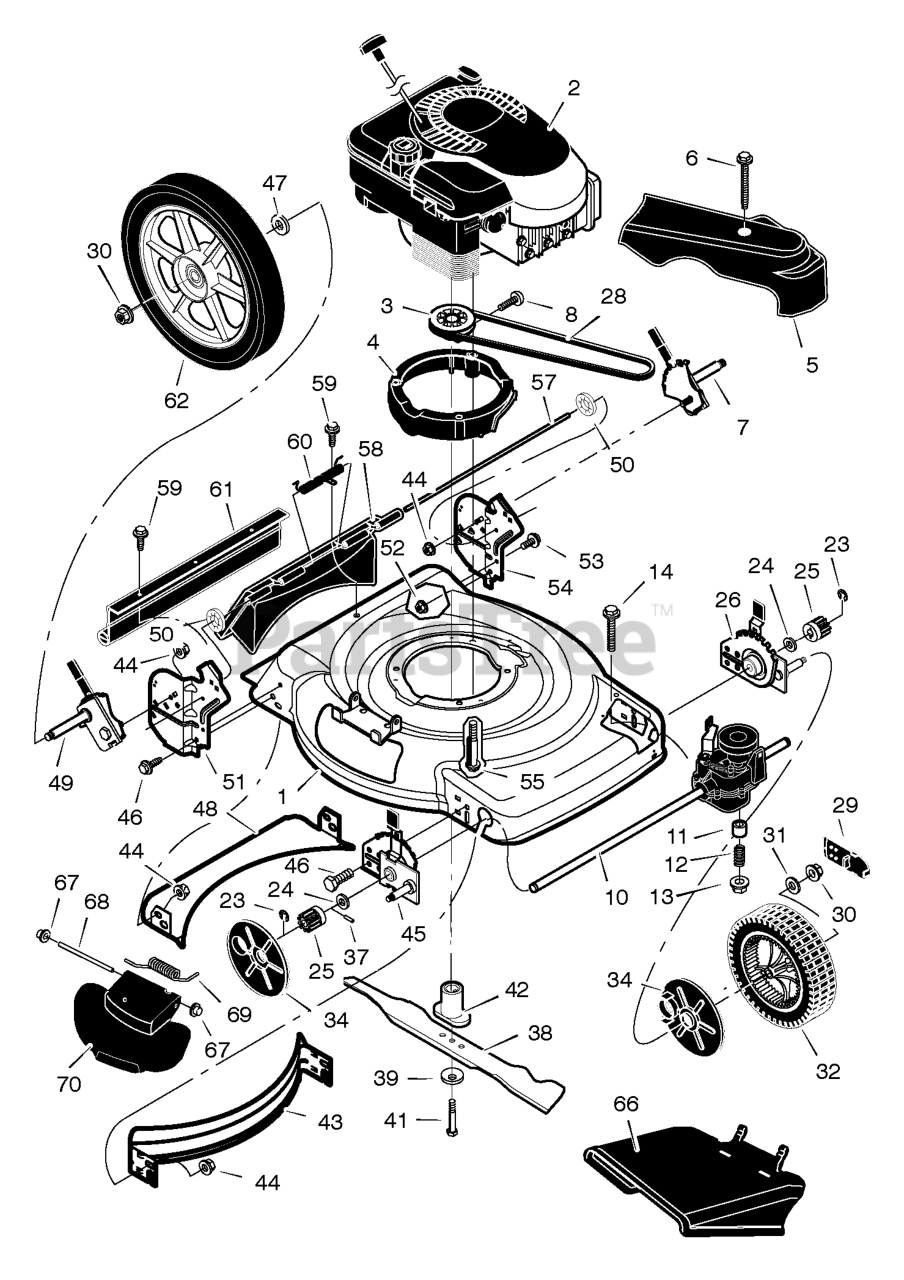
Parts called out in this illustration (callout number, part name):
1	Housing
2	Engine *
3	Pulley, Drive
4	Spacer, Engine
5	Cover, Belt (Black)
6	Screw
7	Adjuster, Left Rear Height
8	Screw
10	Transmission *
12	Spring, Compression
13	Nut
14	Bolt
25	Gear, Pinion
26	Adjuster, Left Front Height
29	Cap, Hub
30	Nut, Flange
31	Washer
32	Wheel & Tire, Front
34	Cover, Dust
37	Pin, Drive
38	Blade
39	Washer, Belleville
42	Adapter, Blade
43	Baffle, Front
44	Nut, Flange
45	Adjuster, Right Front Height
46	Bolt
47	Washer
48	Baffle, Rear
49	Adjuster, Right Rear Height
50	Retainer, Push
51	Bracket, Right Handle
52	Nut, Flange
53	Bolt
54	Bracket, Left Handle
55	Bolt, Engine
57	Rod, Pivot
58	Door, Rear (Black)
60	Spring
61	Guard, Rear
62	Wheel & Tire, Rear
66	Deflector, Chute (Black)
67	Push On Cap
68	Rod, Pivot
69	Spring, Torsion
70	Cover, Mulch (Black)
